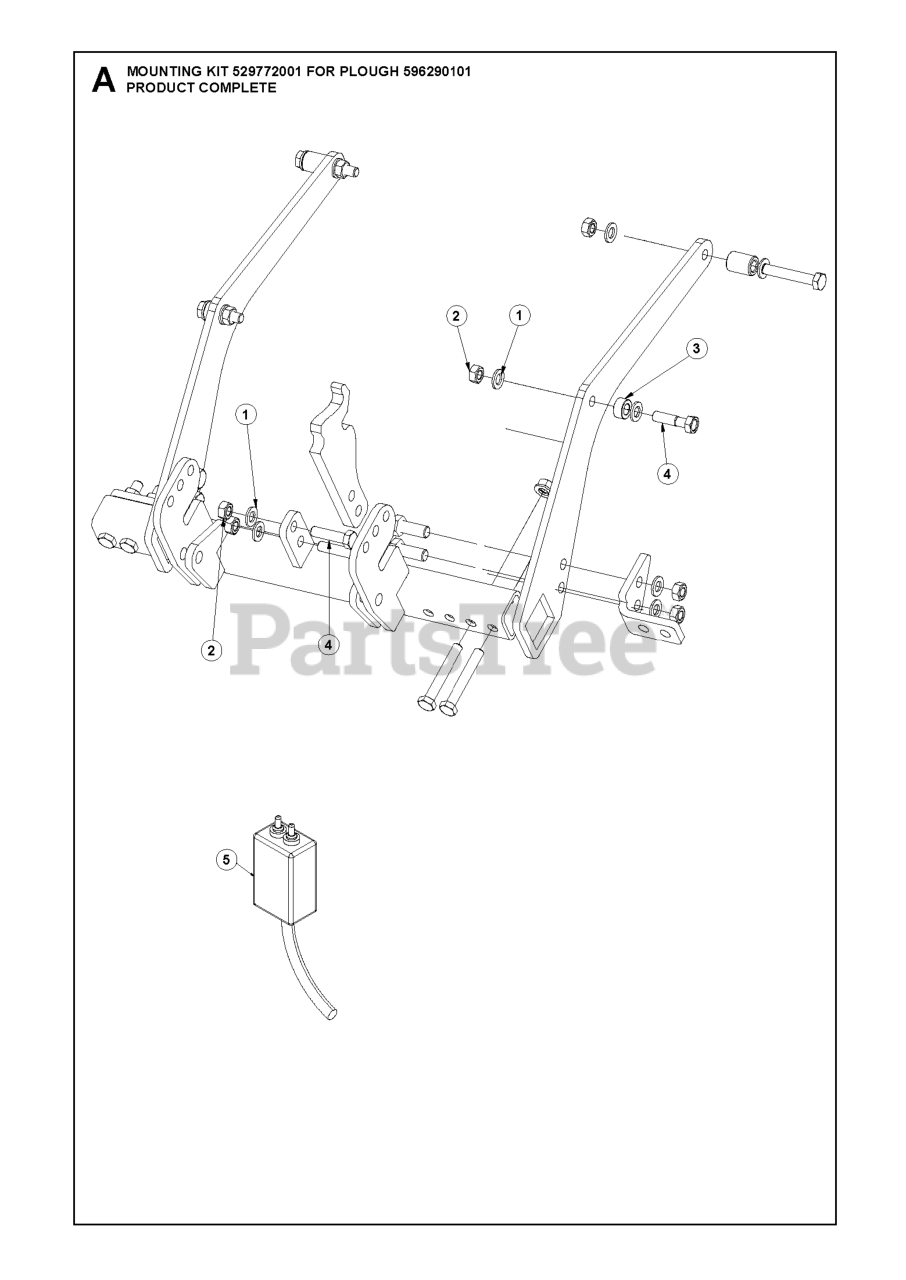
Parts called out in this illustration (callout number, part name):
1	WASHER
2	NUT
4	REPL BY 725 25 00-71
